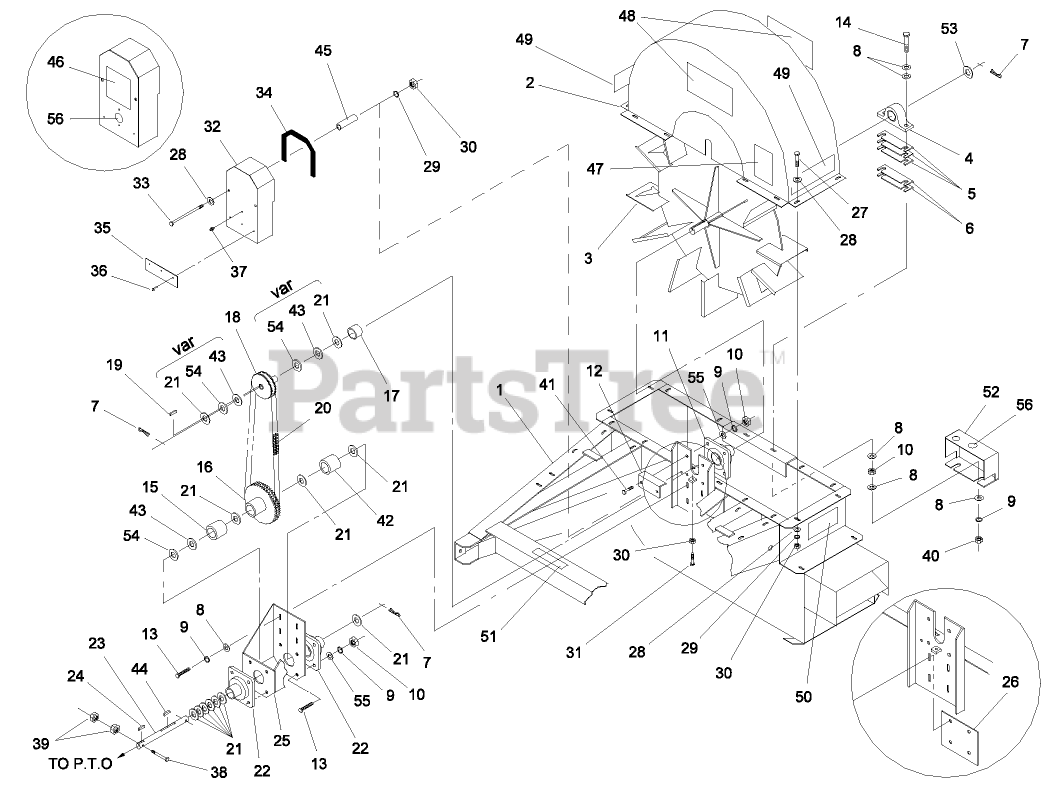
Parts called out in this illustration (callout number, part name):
1	LOWER HOUSING WA
2	FAN HOUSING WA
3	FAN WA R
4	BEARING VPLS124
5	BEARING SHIM
6	BEARING SHIM
7	PIN-COTTER
8	WASHER-FLAT
9	WASHER-LOCK
10	NUT-HH
11	BEARING VF4S124
12	DUST SHIELD
13	SCREW-HH
14	SCREW-HH
15	DRIVE SPACER
16	SPROCKET W/OFFSET KEY
17	FAN SPACER - OUTSIDE
18	SPROCKET DH50B15 1.25B
19	KEY SQ 1/4" X 1 5/8" LG
20	FAN CHAIN
22	BEARING VF4S120
23	LOWER DRIVE SHAFT
24	Key
25	DRIVE HOUSING WA R
26	BACK PLATE R
27	SCREW-HH
28	WASHER-FLAT
29	WASHER-LOCK
30	NUT-HEX
31	HHCS FULL THREAD
32	CHAIN GUARD WA
33	CAPSCREW
35	GEAR BOX FLAP
36	RIVET-POP
37	ZERK
38	SCREW-HH
39	NUT-HEX
40	NUT-JAM
41	SCREW-HH
42	INSIDE SPROCKET SPACER
44	LOWER SPROCKET KEY
45	GUARD SPACER R
46	DECAL-GUARD, CHAIN
47	DECAL-PTO INFORMATION
48	DECAL
49	DECAL - BLOWER 2613
50	DECAL - AIR DEFLECTOR
51	DECAL-DANGER PTO
52	BEARING COVER
53	MACH. BUSHING 1 1/2-10G
55	WASHER-FLAT
56	DECAL-GREASE
